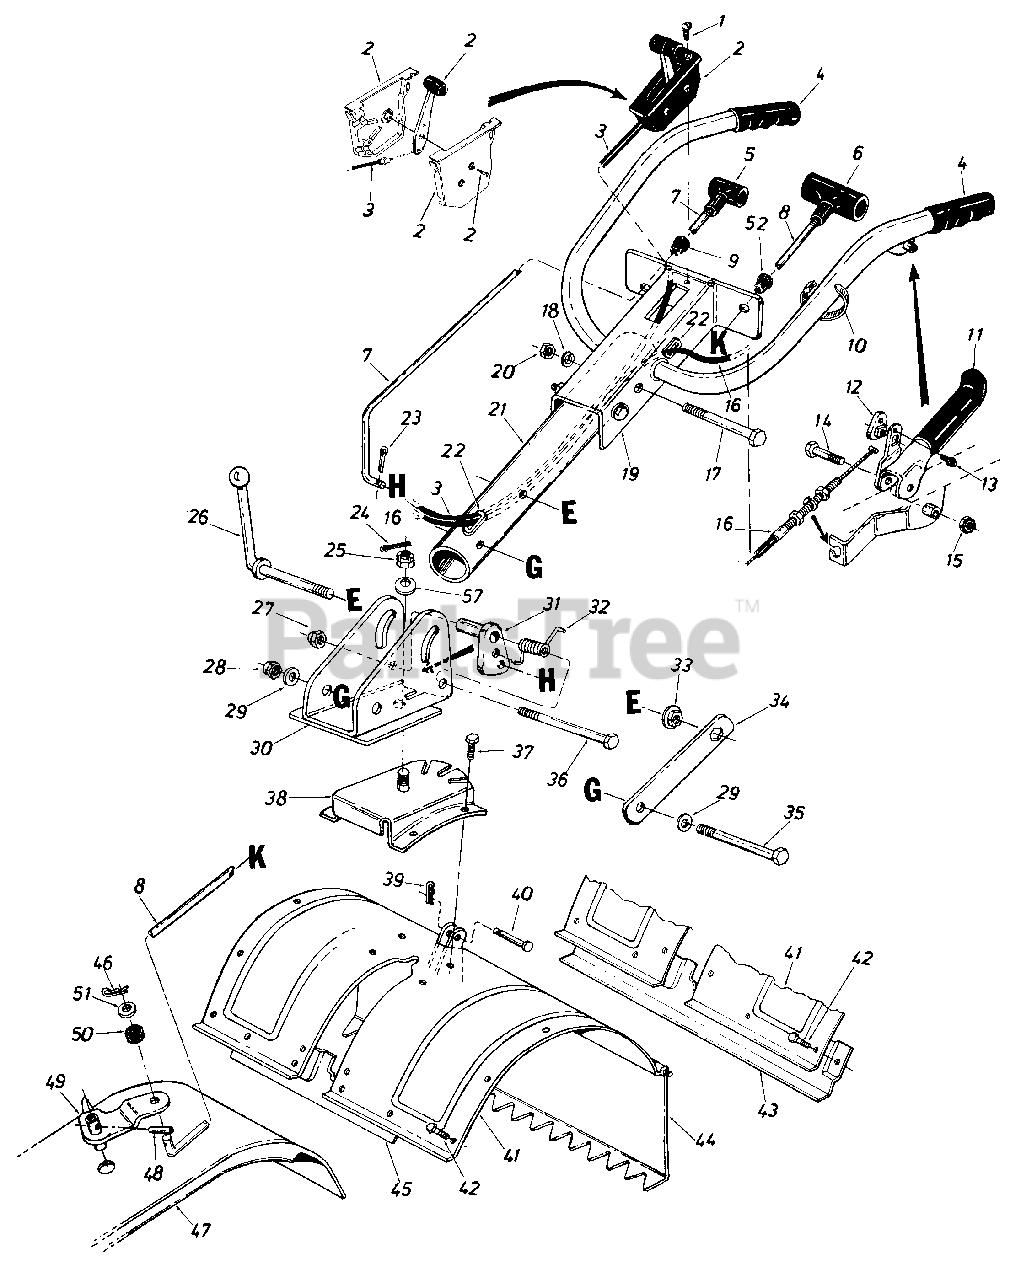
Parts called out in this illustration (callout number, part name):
1	Truss Mach. AB-Tap. Scr. #10 x .50" Lg.
2	Throttle Control Box Ass'y.
3	Throttle Control Wire
4	Handle Grip
5	Small "T" Knob
6	Large "T" Knob
7	Clutch Rod
8	Control Rod 37" Lg.
9	Snap On Bushing 3/8" Dia.
10	Cable Tie-Self Clinching
11	Clutch Grip Ass'y.L.H.
12	Barrel Cable Hold Down
13	Hex B-Tap Scr. #10 x .44" Lg.
14	Hex Bolt 3/8-16 x 2.0" Lg.
15	Hex Cent. L-Nut 3/8-16 Thd.
16	Clutch Control Cable 53" Lg.
17	Hex Bolt 3/8-16 x 3.00" Lg.
18	L-Wash. 3/8" I.D.H.D.
23	Coter Pin 3132" Dia. x .75" Lg.*
24	Cote;Pin 3132" Dia. x 1.25" Lg.
25	Hex Sloted Nut 5/8-18 Thd.
26	Handle Adj. Crank
27	Hex Cent. L-Nut 3/8-16 Thd.
28	Hex Nut 3/8-16 Thd.
29	Bell-Wash. .400" I.D. x .87" O.D.
30	Handle Pivot Bracket
31	Positioner Crank Ass'y.
32	Spring Handle Adj.
33	Hex Flange Nut 3/8-24 Thd.
34	Bracket Hex Nut Retainer
35	Hex Bolt 3/8-16 x 3.25" Lg.
36	Hex Bolt 3/8-16 x 3.00" Lg. Grade 8
37	Hex Bolt 3/8-16 x .75" Lg.
38	Handle Positioner Brkt. Ass'y.
39	Intern. Coter Pin
40	Clevis Pin .375" Dia.
43	Bracket Reinforcement-18"
46	Intern. Coter Pin 5/16" Dia.
47	Shift Cover
48	Spring Roll Pin 3116" Dia. x 1.00" Lg.
49	Shifting Crank Ass'y. D x 2.05
50	Rubber Washer .33" I.D. x .87" O.D.
51	Fl-Wash. .400" I.D. x 1.250" O.D
52	Snap On Bushing 1/2" Dia.
57	Bell-Wash. .630" I.D. x 1.25" O.D.
